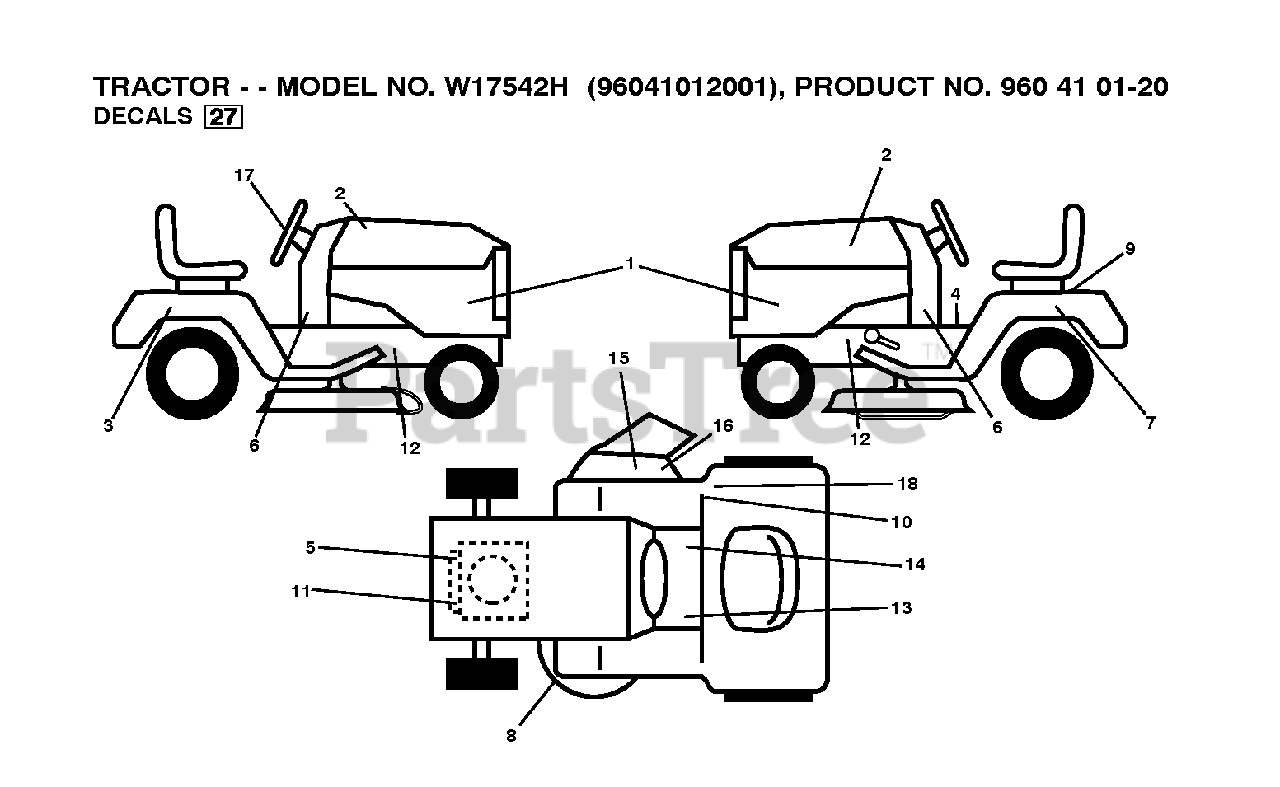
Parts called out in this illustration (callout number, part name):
6	DECAL.CHAS.TURBO
8	DECAL V BELT SCHEMATIC
9	DECAL BTRY SYMBOLS
10	DECAL 80 DBA
14	DECAL PARK BRAKE
15	DECAL.INTERNATIONL.CUTFINGER
16	DECAL, DEFLECT WARNING
